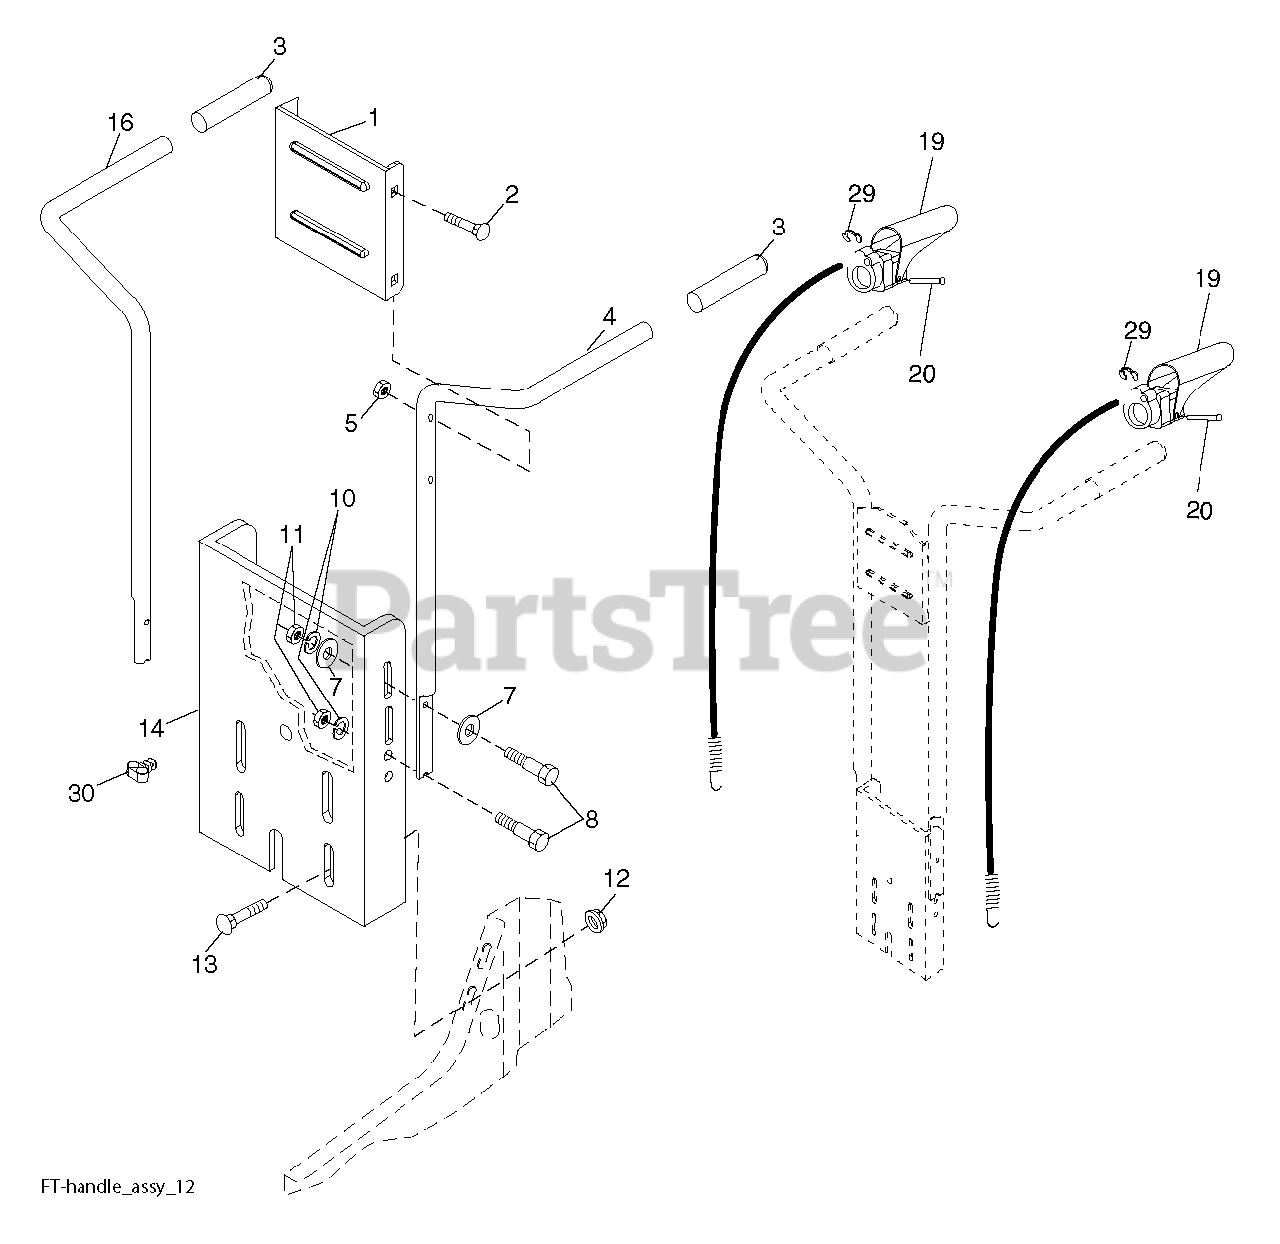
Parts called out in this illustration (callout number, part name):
1	BRACKET.HANDLE.ORANGE
2	BOLT
3	GRIP.HANDLE.BLACK
4	HANDLE.PNT.LH.DOUBLE.BEND
5	NUT.LOCK.5/16-18
7	WASHER
8	BOLT
10	LOCKWASHER
12	NUT
13	BOLT, RDHD SQNK 5/16-18 X 3/4
14	PANEL.PNT.HANDLE.ORANG.MS668
16	HANDLE.PNT.RH.DOUBLE.BEND
19	CONTROL ASM.TINE.49.88
20	PIN, PIVOT
29	RETAINING.RING.#5103-25
30	CLIP.ROUTING DUAL
